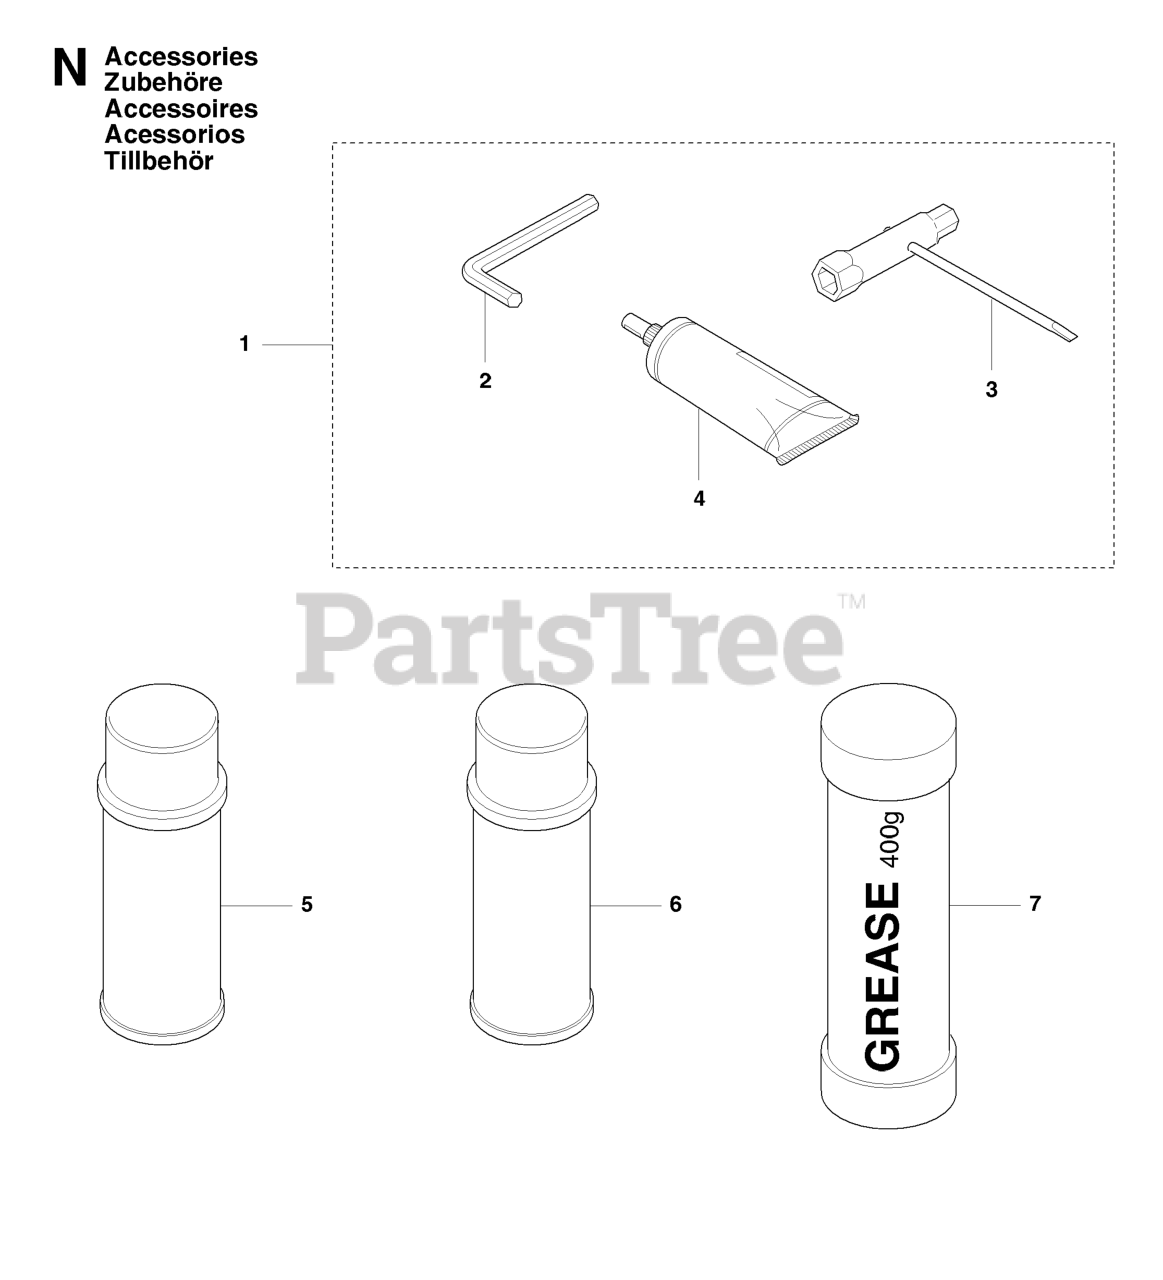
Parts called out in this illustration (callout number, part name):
3	COMBI TOOL
5	Ul 22 - 12 Pack
6	CUTTER BAR LUBE/12 PACK UL21
7	Grease 400 Grams
